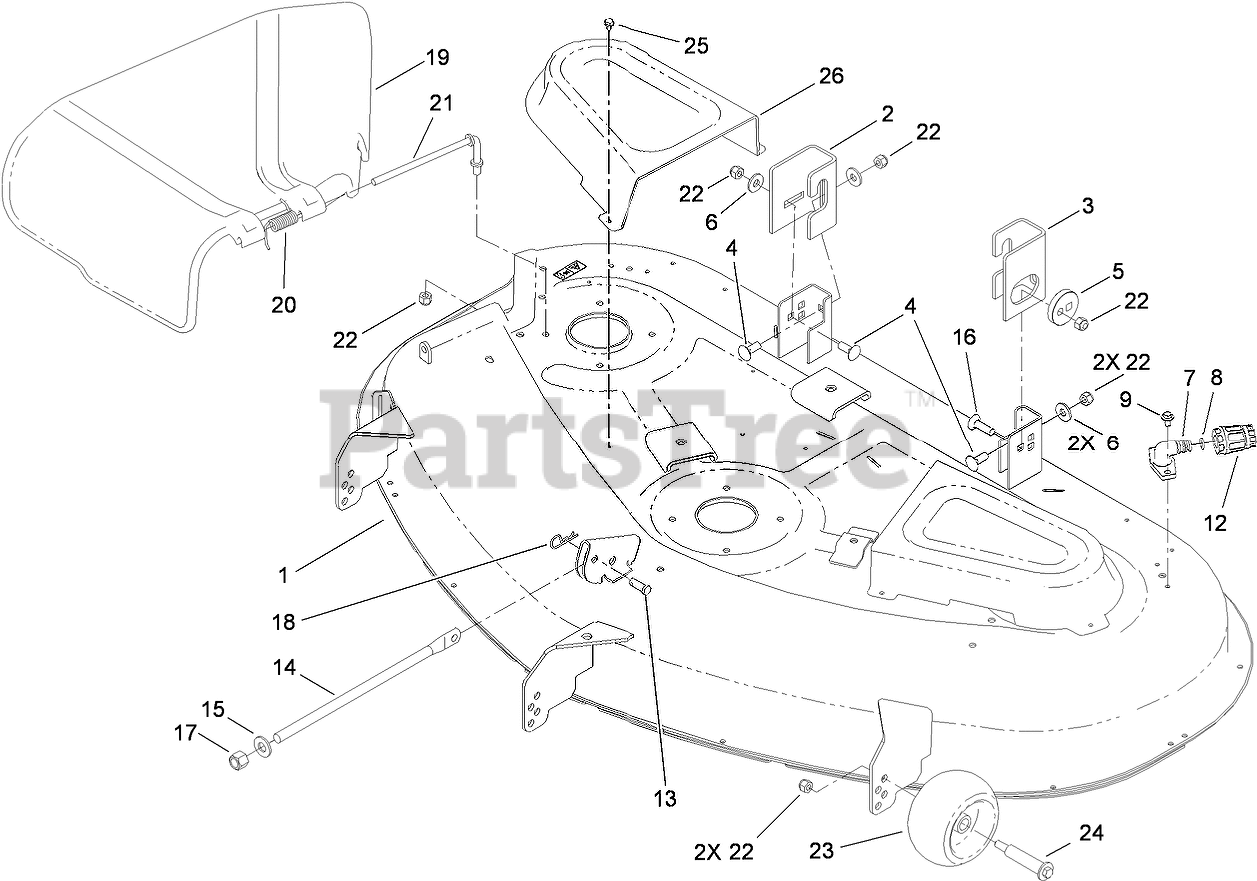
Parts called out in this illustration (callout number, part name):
1	50 INCH DECK ASM
2	BRACKET-HANGER, RIGHT REAR
3	BRACKET-HANGER, LEFT REAR
4	BOLT-CARR
5	ECCENTRIC
6	WASHER-HARDENED
7	FITTING-WASHOUT
8	O-RING
9	SCREW-HHFTF
12	CONNECTOR-HOSE
13	PIN-CLEVIS
14	ROD-LIFT
15	WASHER-THRUST
16	SCREW-CARR
17	NUT-LOCK, NI
18	PIN-HAIR
19	DEFLECTOR
20	SPRING-TORSION
21	ROD-PIVOT
22	NUT-LOCK, NI
23	ROLLER-SCALP, ANTI
24	BOLT-SHOULDER
25	SCREW-HWHTF
26	COVER-BELT
